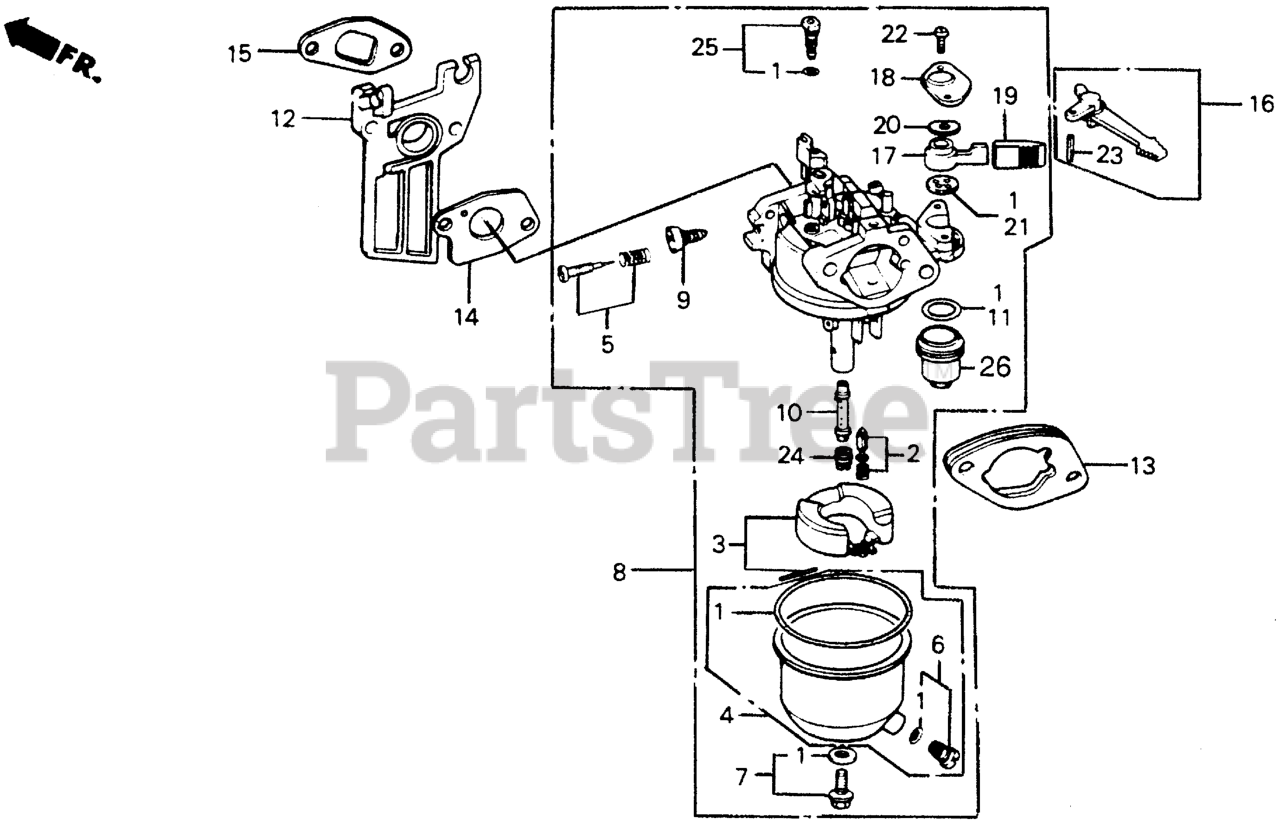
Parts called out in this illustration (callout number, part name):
1	GASKET SET
2	VALVE SET, FLOAT (CARBURETOR NO.) (SEAT NOT INCLUDED)
3	FLOAT SET
4	CHAMBER SET, FLOAT (CARBURETOR NO.)
4	CHAMBER SET, FLOAT (CARBURETOR NO.) (FOR BE12A A)
5	SCREW SET, PILOT (Honda Code 1441500). (CARBURETOR NO.)
6	SCREW SET, DRAIN (Honda Code 1672187). (CARBURETOR NO.)
7	SCREW SET B
7	SCREW SET
8	CARBURETOR ASSY. (BE07A C)
8	CARBURETOR ASSY. (BE07A D)
8	CARBURETOR ASSY. (BE07A E)
9	SCREW, THROTTLE STOP
10	NOZZLE, MAIN
11	GASKET, FUEL STRAINER CUP
12	INSULATOR, CARBURETOR
13	SPACER, CARBURETOR
14	GASKET, CARBURETOR
15	GASKET, INSULATOR
16	LEVER, CHOKE (REMOTE)
17	LEVER, VALVE
18	PLATE, LEVER SETTING (CARBURETOR NO.)
19	CAP, LEVER
20	SPRING, PETCOCK LEVER (CARBURETOR NO.)
21	GASKET, VALVE
22	SCREW, PAN (3X8)
23	PIN, SPRING (2X12)
24	JET, MAIN (#65) Use up to Engine SN BB30A D.
24	JET, MAIN (#68) Use up to Engine SN BB30A D.
24	JET, MAIN (#70) Use up to Engine SN BB30A D.
25	JET SET, PILOT (#35)
